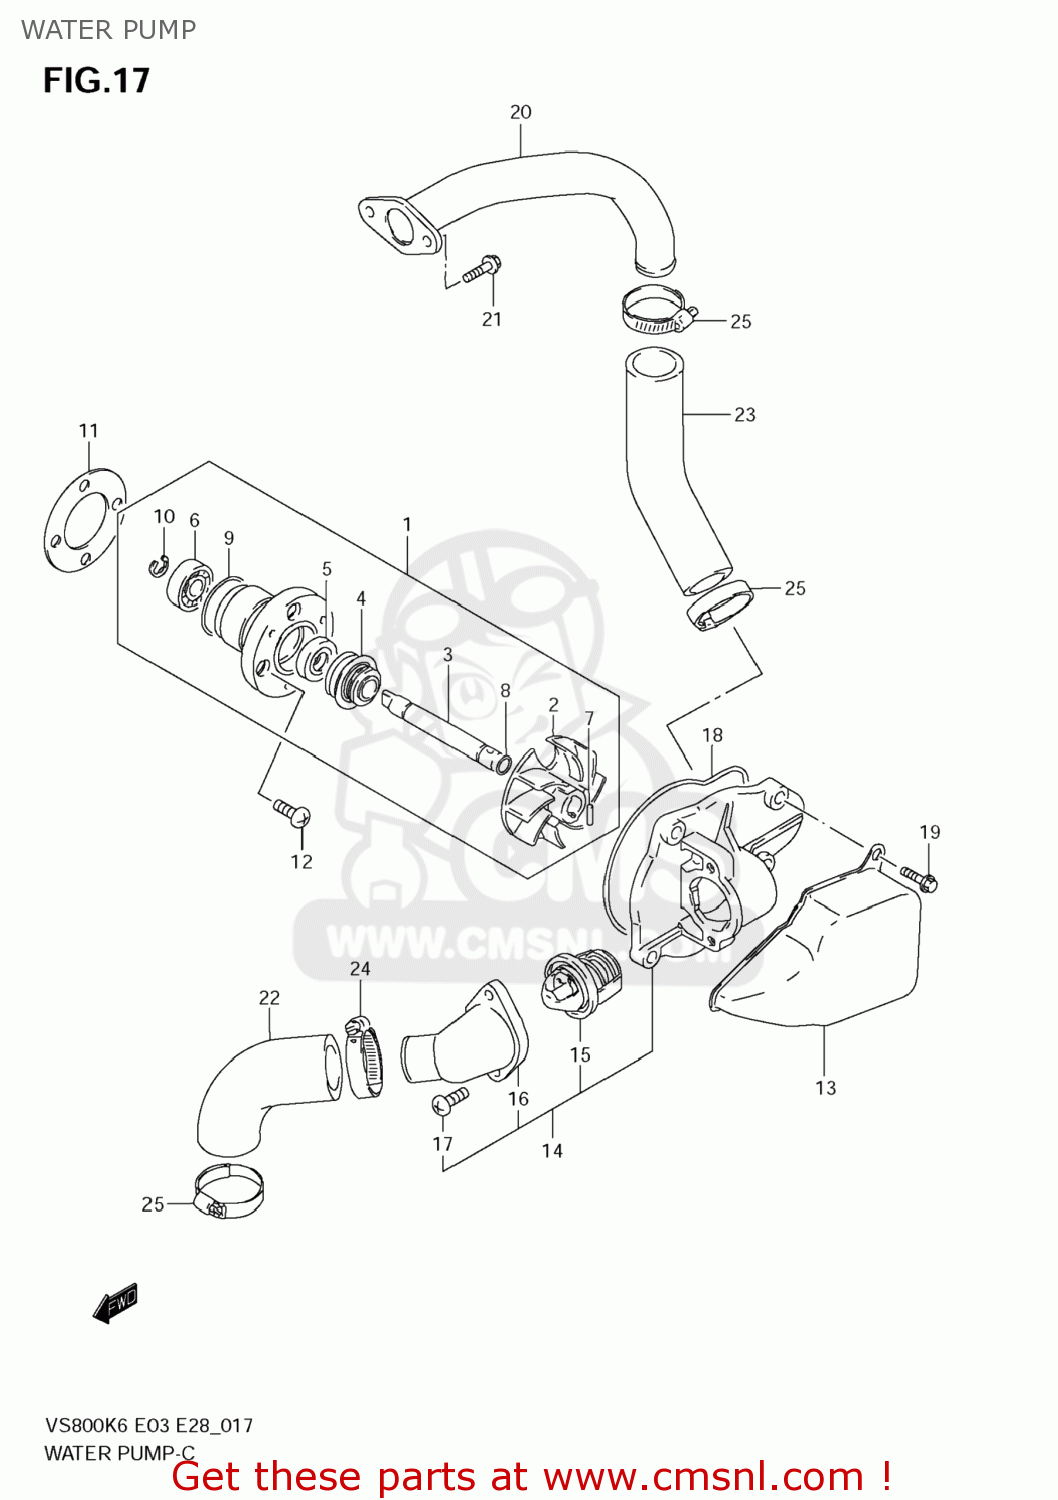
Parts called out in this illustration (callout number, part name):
1	PUMP ASSY,WATER
2	IMPELLER
3	SHAFT
4	SEAL,MECHANICAL
5	SEAL,OIL(10X21X5)
6	BEARING(10X22X6)
7	PIN
8	O RING
9	O RING
10	E RING
11	GASKET,WATER PUMP (NAS)
12	SCREW
13	COVER,WATER PUMP
14	CASE ASSY,WATER PUMP
15	THERMOSTAT,WATER
16	CONNECTOR
17	SCREW
18	O RING,WATER PUMP CAP
19	BOLT
20	PIPE,CYLINDER INLET
21	BOLT
22	HOSE,WATER PUMP IN
23	HOSE,WATER PUMP OUTLET
24	CLAMP
25	CLAMP
